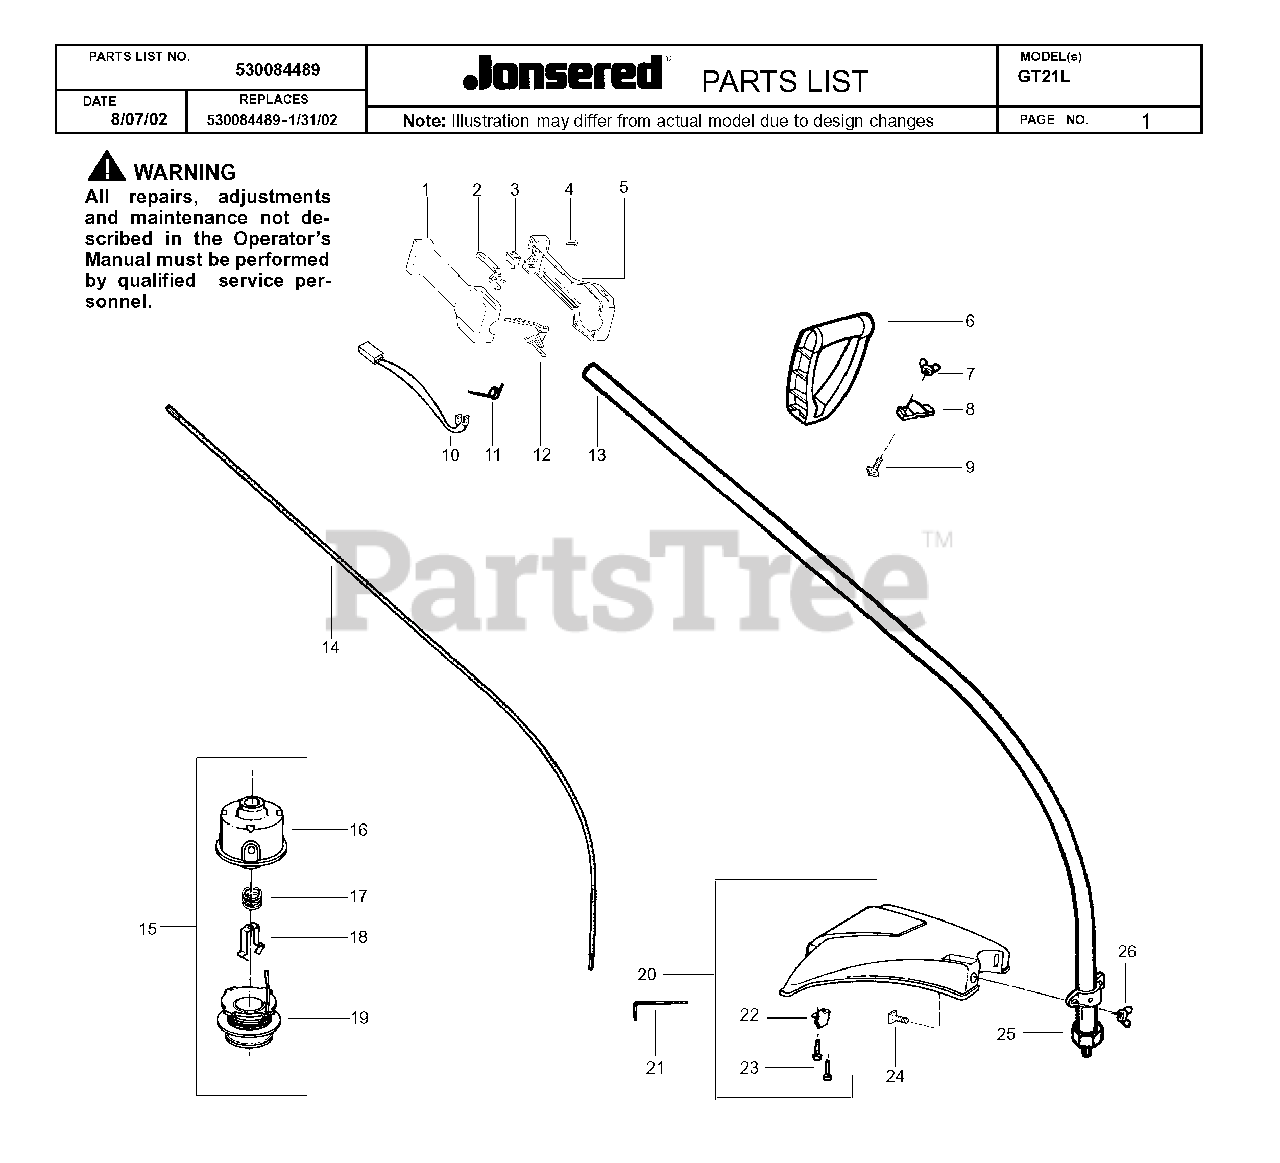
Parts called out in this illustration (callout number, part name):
4	SCREW-10-14 X 13/16 (PL
6	"D" HANDLE
7	NUT - HANDLE/SHIELD
8	CLAMP-ASSIST HANDLE
9	BOLT, TYPE 2
12	THROTTLE TRIGGER
21	HEX WRENCH 5/32
22	LINE CUTTER
24	BOLT, TYPE 2
26	NUT - HANDLE/SHIELD
